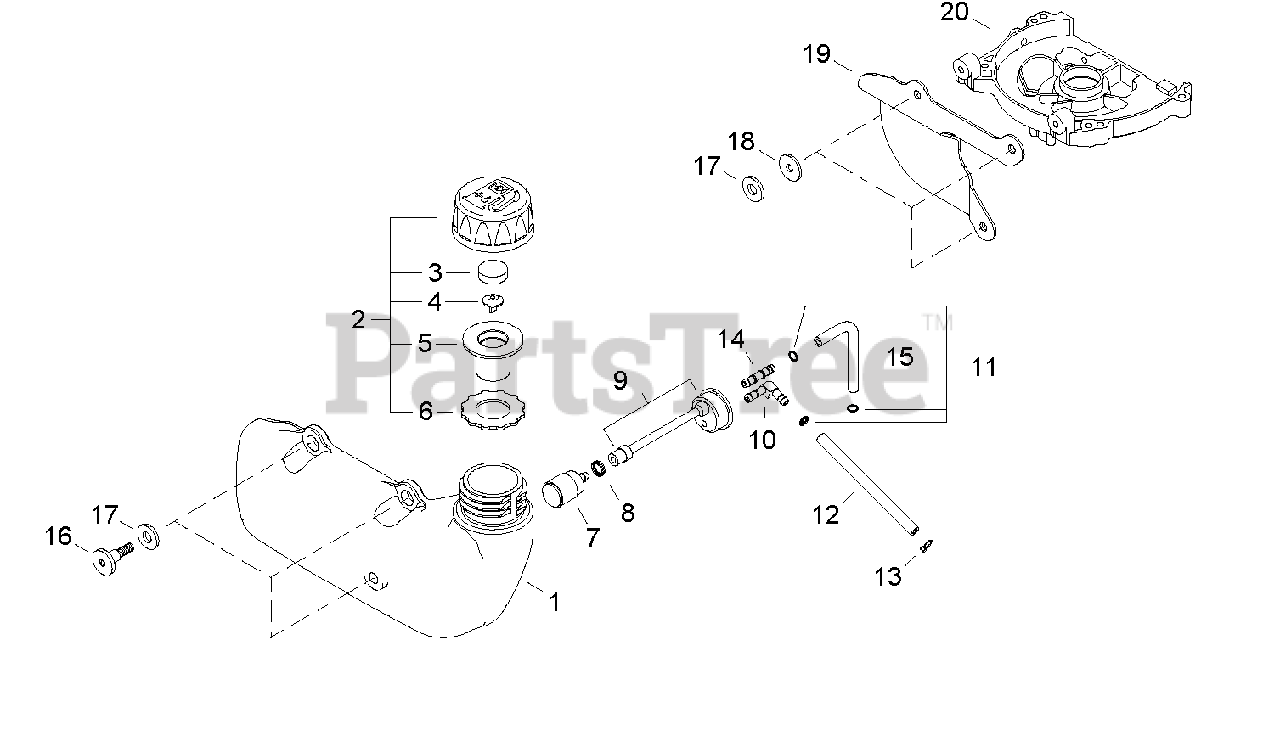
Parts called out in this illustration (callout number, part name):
1	TANK, FUEL
2	CAP, FUEL
3	PACKING, VENT
4	VENT ASSY
5	HOLDER, VENT
6	GASKET, FUEL CAP
7	FILTER, FUEL 125-528
9	GROMMET, FUEL WITH PIPE
10	CONNECTOR, PIPE
11	CLIP Ø6
12	PIPE, FUEL RETURN
13	CLIP, SPRING Ø5.2
14	CONNECTOR, PIPE
15	PIPE, FUEL
16	BOLT, ADHESIVE 5
17	WASHER 6
18	WASHER 5
19	SHIELD, HEAT
20	CRANKCASE ASSY, M
